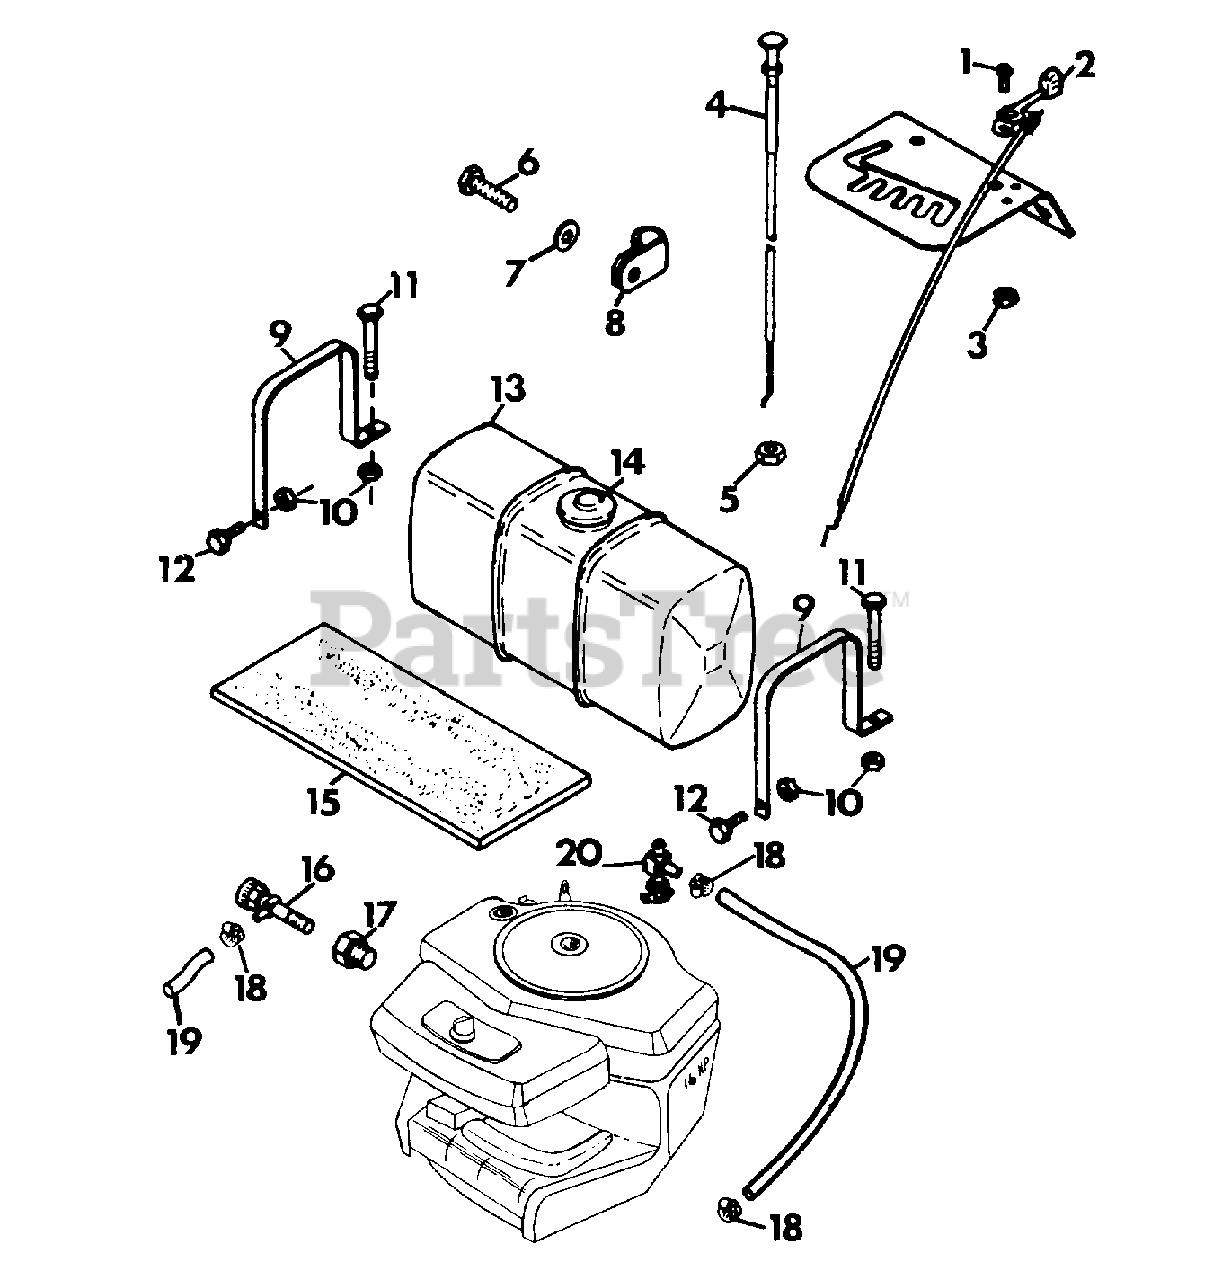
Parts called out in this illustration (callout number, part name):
1	SCREW, MACH. 10-24X.50 PHD
2	LEVER, CONTROL
3	NUT, LOCK 10-24
4	CONTROL, CHOKE
5	NUT, JAM 3/8-24 HEX HEAD
6	BOLT, HEX 1/4-20X1.00
7	WASHER, FLAT .281X.625X.065
8	CLAMP
9	STRAP, FUEL TANK
10	NUT, LOCK 1/4-20
11	BOLT, HEX 1/4-20X1.75
12	BOLT, HEX 1/4-20X.625
13	TANK, FUEL (12 QTS.)
14	CAP, FUEL TANK
15	PAD, FUEL TANK
16	COCK, OIL DRAIN
17	ADAPTOR, OIL DRAIN
18	CLAMP, HOSE
19	LINE, FUEL
20	VALVE AND STRAINER
